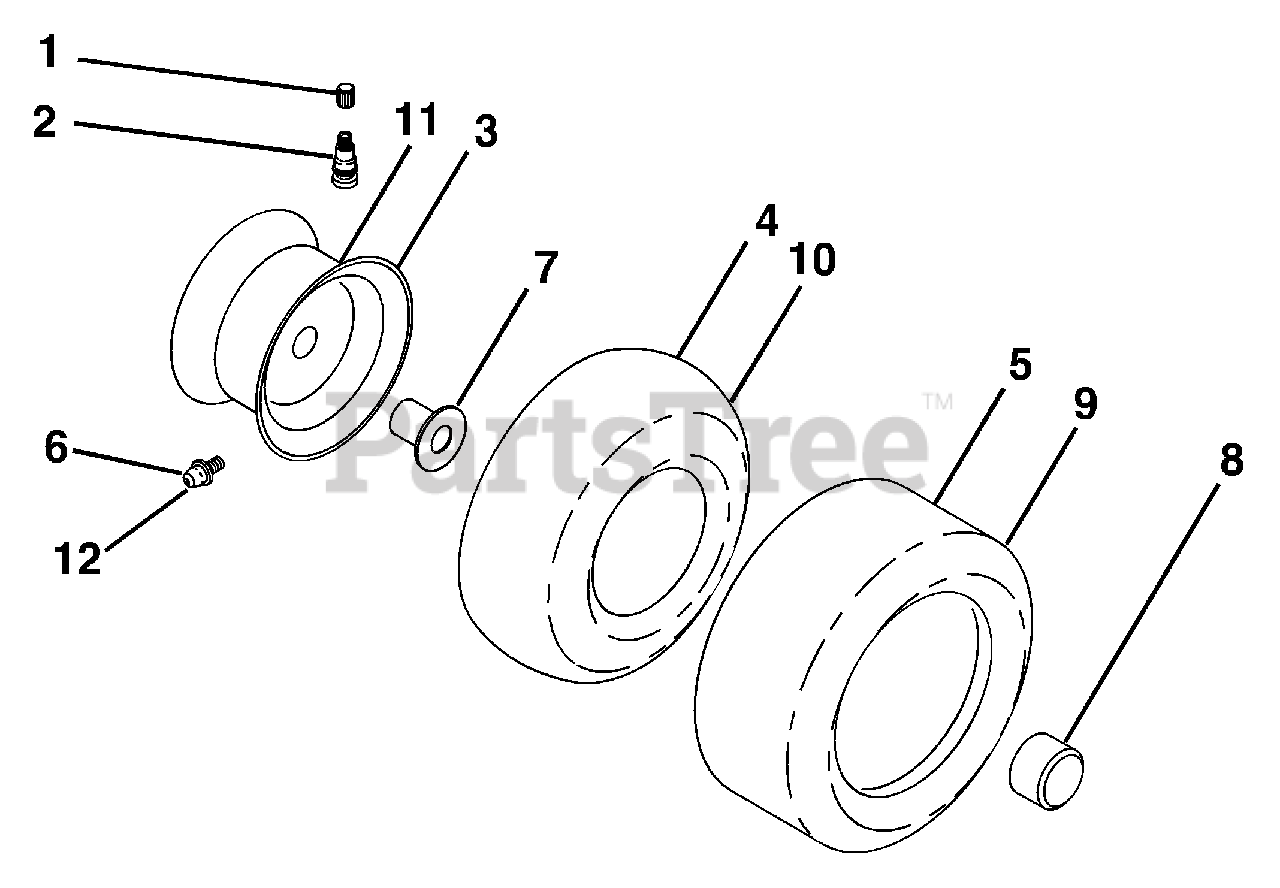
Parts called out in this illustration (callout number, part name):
1	Cap, Valve, Tire
2	Stem, Valve
3	Rim Assembly, Front
4	Tube, Front (Service Item Only)
5	Tire, Front
6	Fitting, Grease
7	Bearing, Flange (Front Wheel Only)
8	Cap, Hub
9	Tire, Rear
10	Tube, Rear (Service Item Only)
11	Rim Assembly, Rear
12	Fitting, Grease
